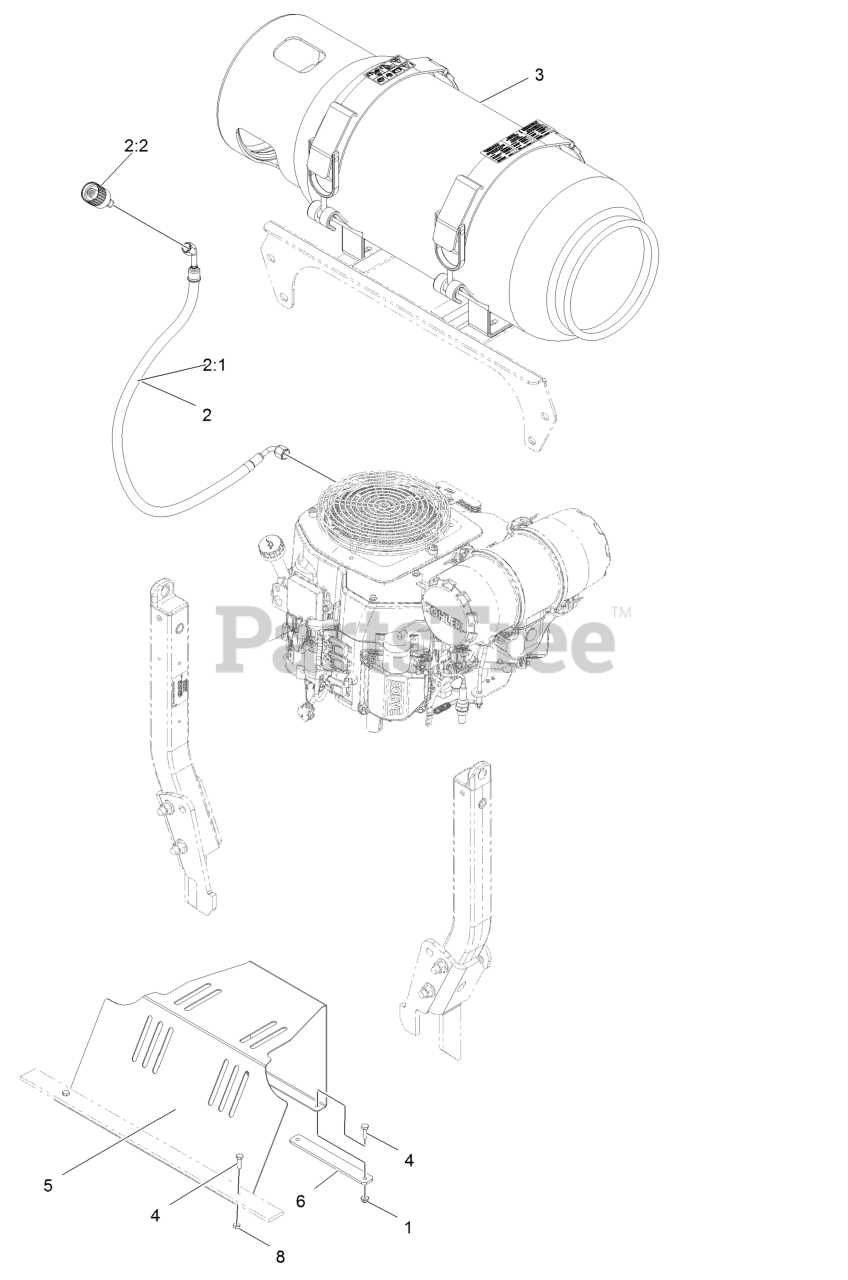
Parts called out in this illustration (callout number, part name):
1	Nut-Nyloc 1/4-20 Flg
2	LPG Hose ASM
2:1	Hose ASM, LPG
2:2	Connector-LP, Straight
3	Tank-LPG
4	Screw-HH 1/4-20 X 7/8
5	Sheild-Fan
8	Nut-Jam 1/4-20
